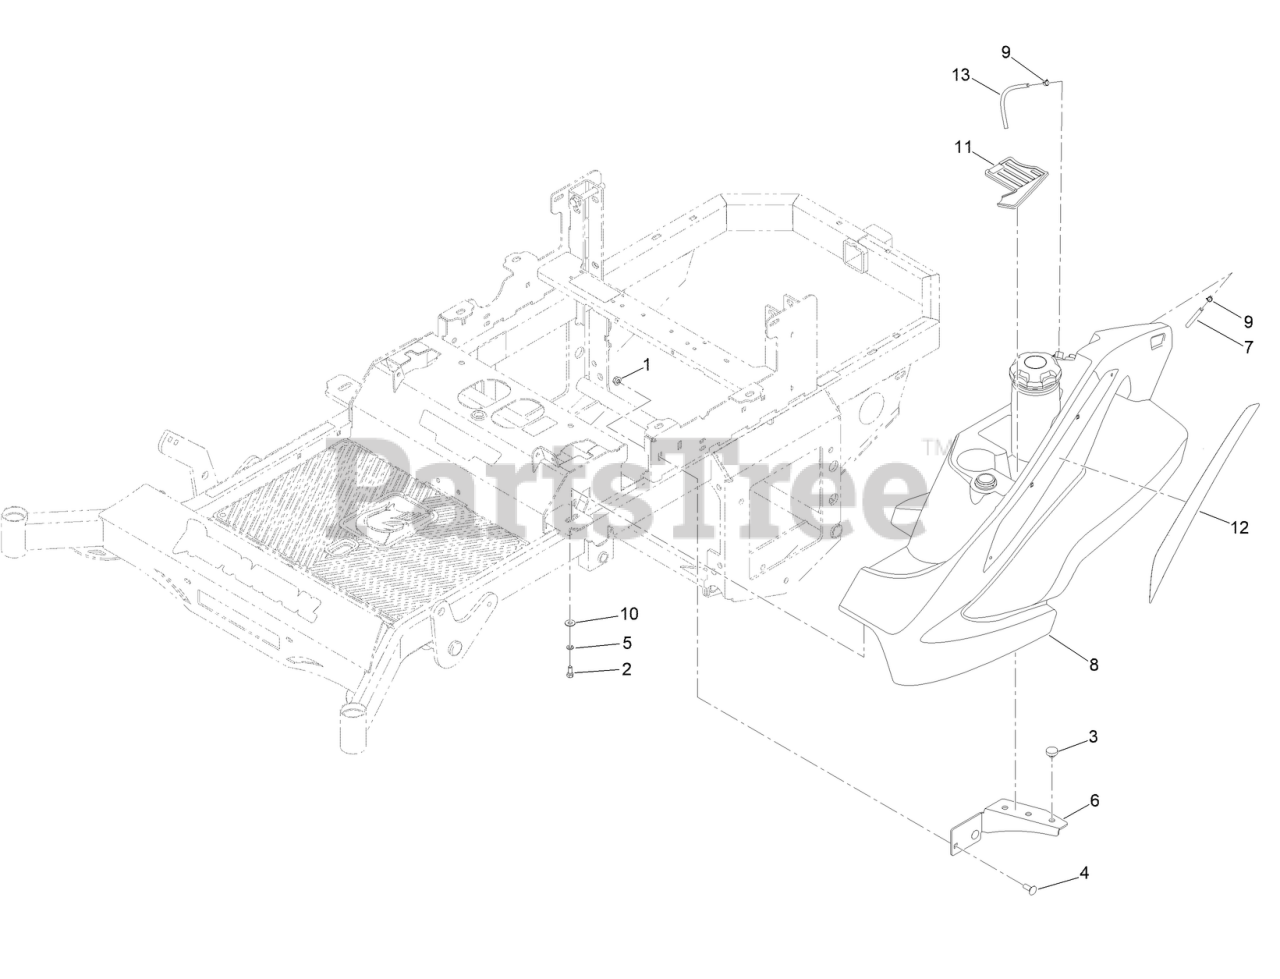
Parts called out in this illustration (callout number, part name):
1	3/8-16 HEX FLANGE NUT W/SERR ZINC YELLOW
2	SCREW-HH
3	PUSH-IN RUBBER BUMPER MWR FLOOR
4	3/8-16 X 1 CARRIAGE BOLT YZ GR.8
5	WASHER-LOCK
6	RT/SRT GAS TANK SUPPORT PAINTED
7	MWR FUEL TANK BLACK 3/16IN VENT TUBE 1FT
8	MWR GASOLINE FUEL TANK ASSY
9	1/2IN (#8) HOSE CLAMP
10	WASHER-FLAT
11	RUBBER TANK STORAGE COMPARTMENT INSERT
12	DECAL-TANK
13	1/4IN SAE J30R7 BULK HOSE 1FT
